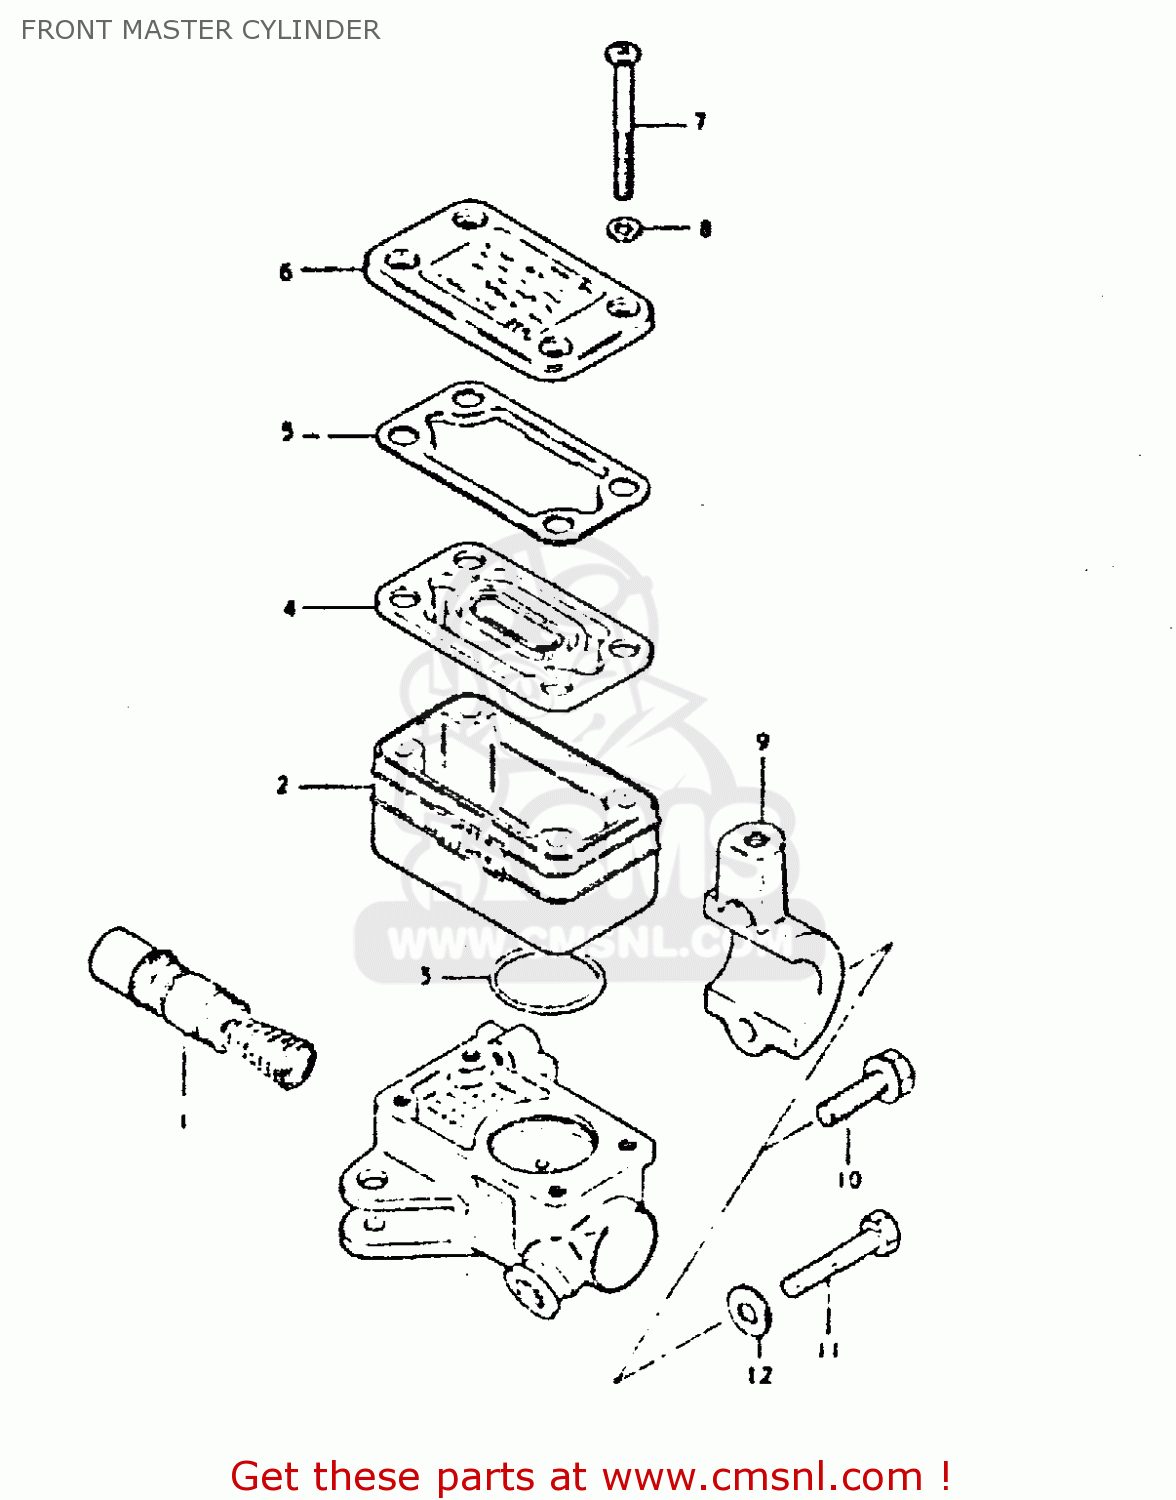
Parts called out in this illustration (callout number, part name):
1	PISTON & CUP SET
2	RESERVOIR
3	O RING
4	DIAPHRAGM
5	PLATE,DIAPHRAGM
6	CAP
7	SCREW
8	WASHER
9	HOLDER
10	BOLT,MASTER CYLINDER H
11	BOLT
12	WASHER
